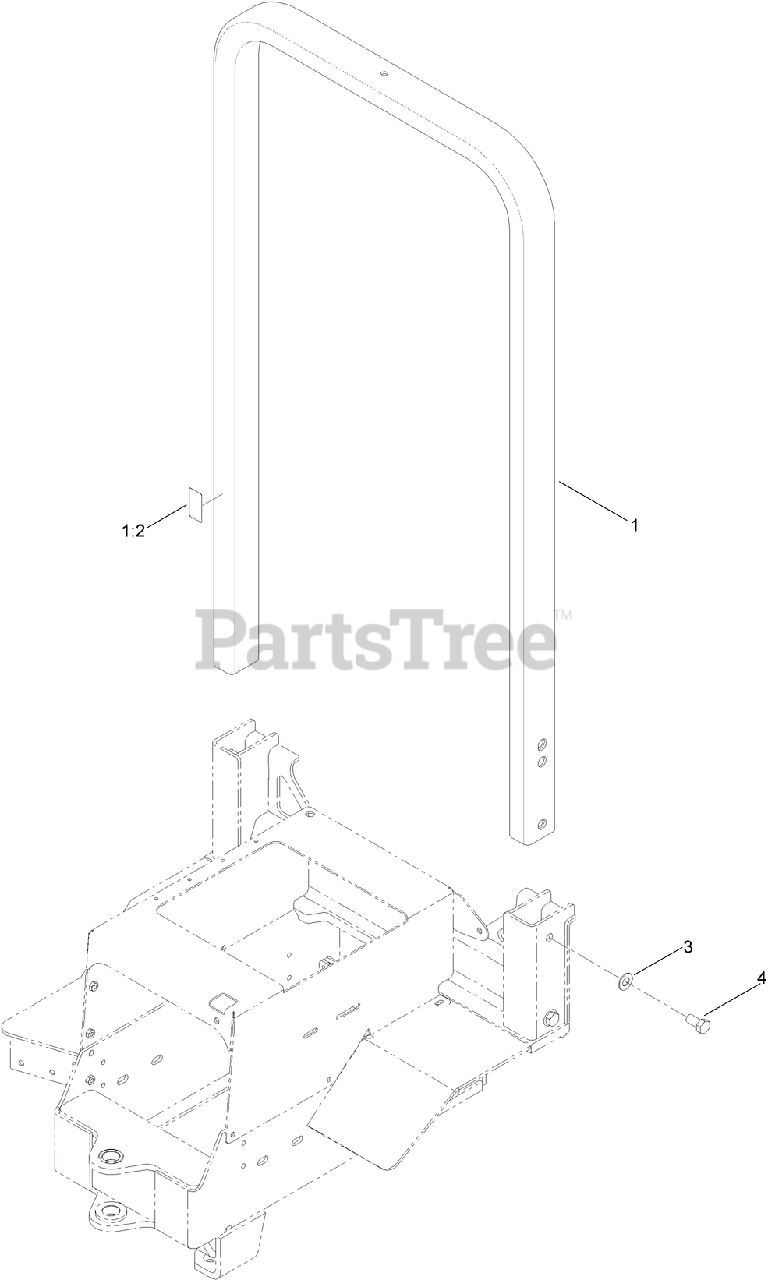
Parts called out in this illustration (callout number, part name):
1	ROPS ASM
1:2	DECAL-ROPS
3	WASHER-FLAT
4	SCREW-HH
